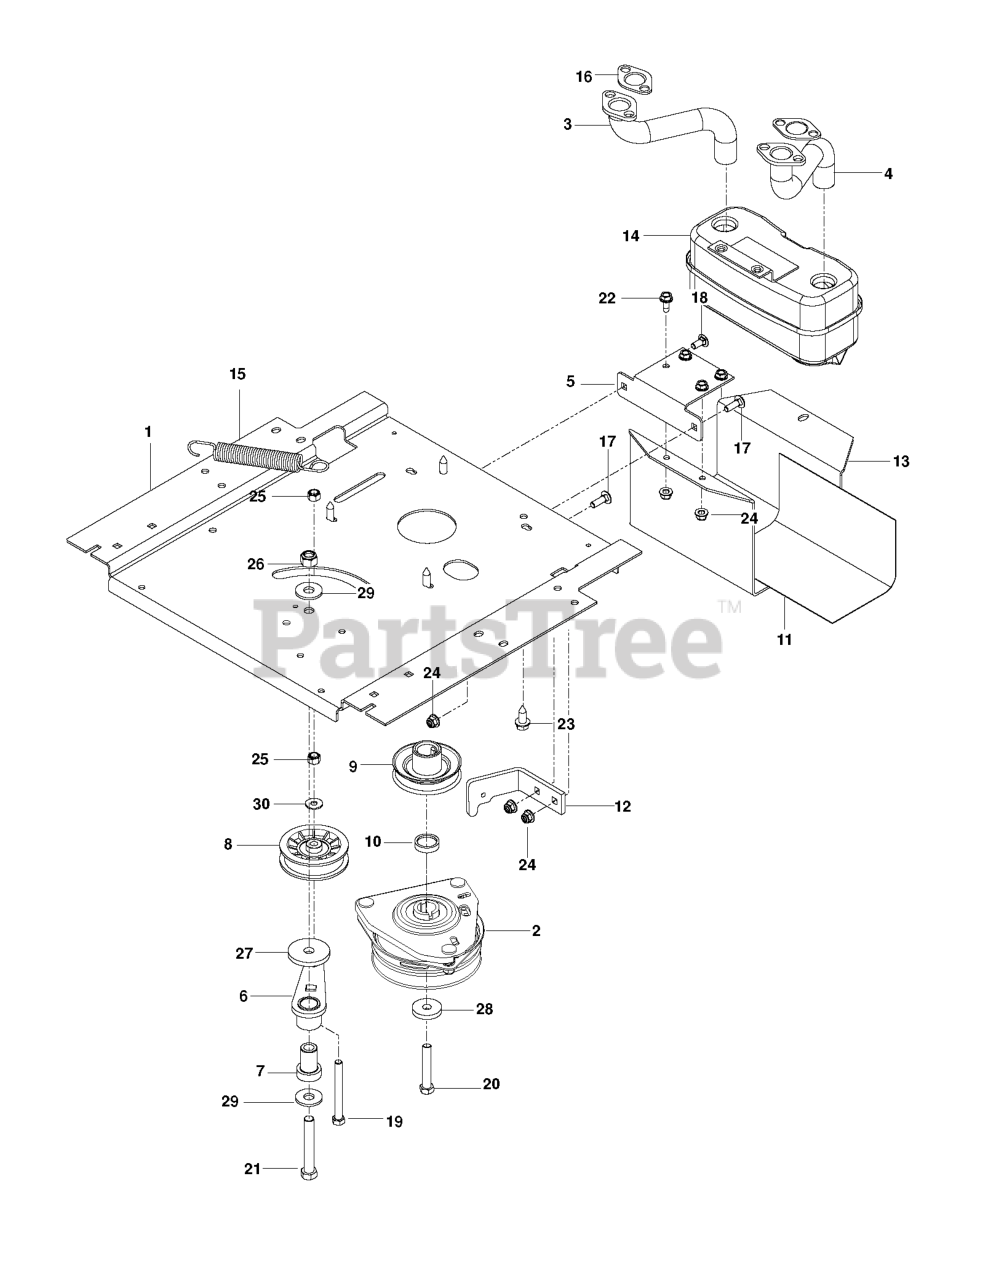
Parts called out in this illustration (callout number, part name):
1	PLATE ENGINE, BLACK
2	Clutch, Ogura 5.0Pd Gt1.5A-Eh07
3	Exhaust Tube, RH B&S Twin Intek
4	Exhaust Tube, LH.Bs/Twin
5	BRACKET, MUFFLER, BLACK
6	Idler Arm
7	IDLER SPINDLE
8	PULLEY, IDLER
9	Engine Pulley
10	Spacer, 625 Ogura LCC
11	HEAT SHIELD
12	CLUTCH STOP OGR BLK
13	Muffler Guard
14	MUFFLER ASM TWIN
15	SPRING, DECK DRIVE
16	GASKET.MUFFLER
17	BOLT
18	BOLT
19	Hex Capscrew, 3/8-16X3-1/2 Tapblt Gr5 Zd
20	Clutch Bolt, 7/16-20 X 2.5 Gr 5 24Hr
21	Hex Capscrew, 1/2-13 X 3-1/4 Gd 5 Zd
22	SCREW
23	SCREW 3/8-16X1
24	5/16-18 NYLOC FLANGE NUT
25	NUT 3/8-16 NYLOC
26	NUT
27	HEAVY WASHER
29	Washer, 9/16 X 1 3/8 X 12 Ga
30	WASHER
